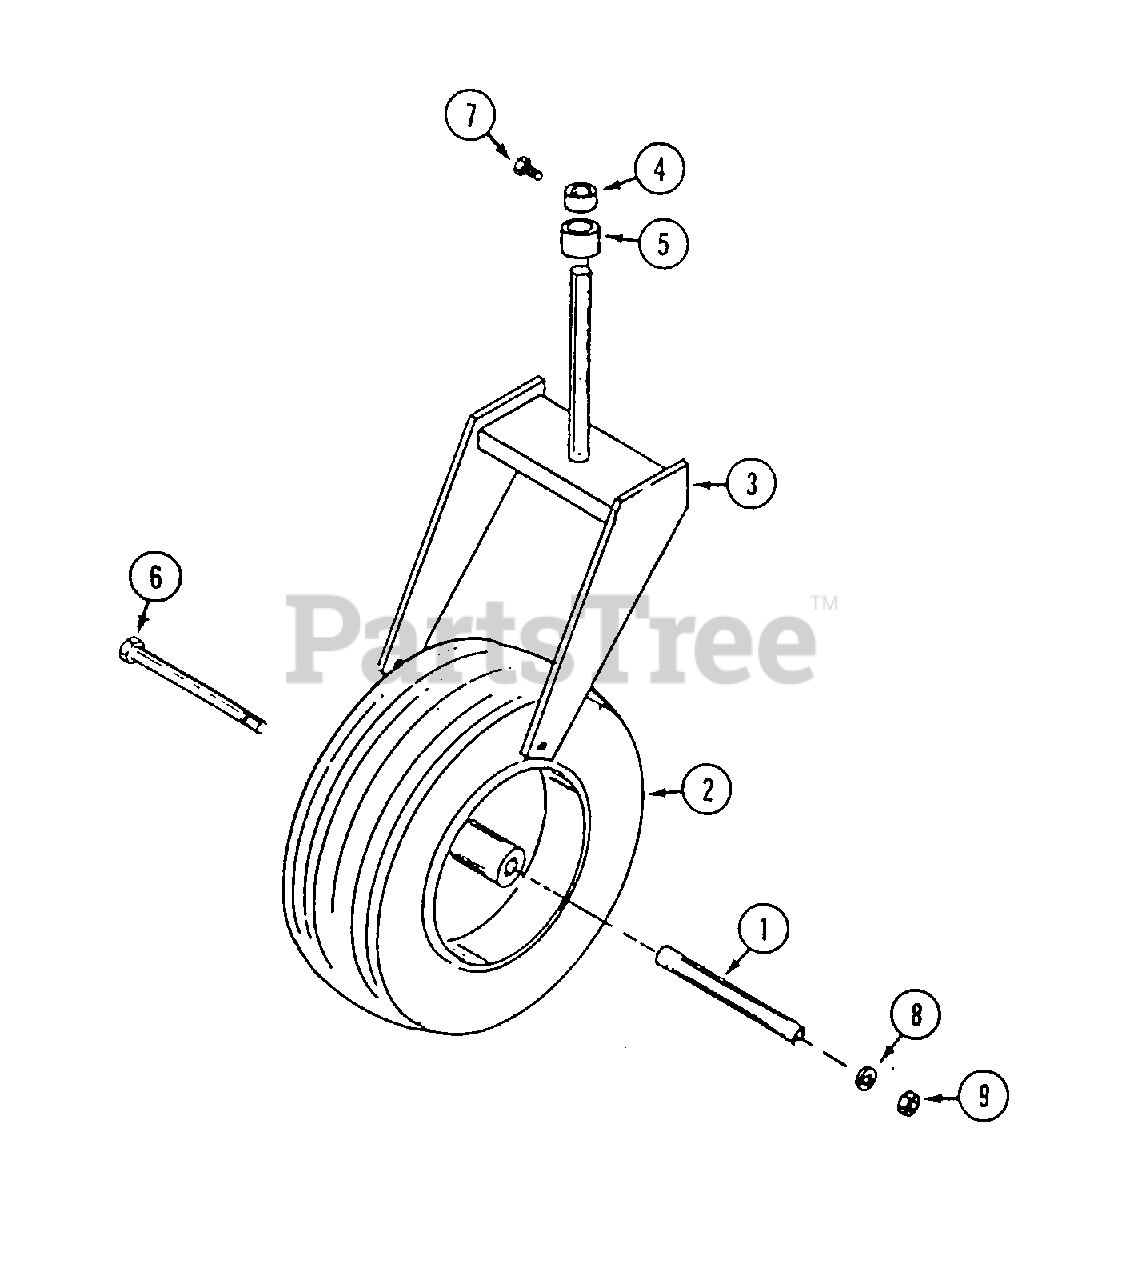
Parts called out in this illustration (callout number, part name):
2	WHEEL ASSEMBLY - tail
3	FORK - tail wheel
4	COLLAR - set 1"
5	SPACER - tail wheel fork
6	BOLT - 1/2" - 13 x 8-1/2"
7	SCREW -set 5/16" - 18 x 1/2" square head
8	LOCKWASHER - 1/2"
9	NUT - 1/2" - 13
